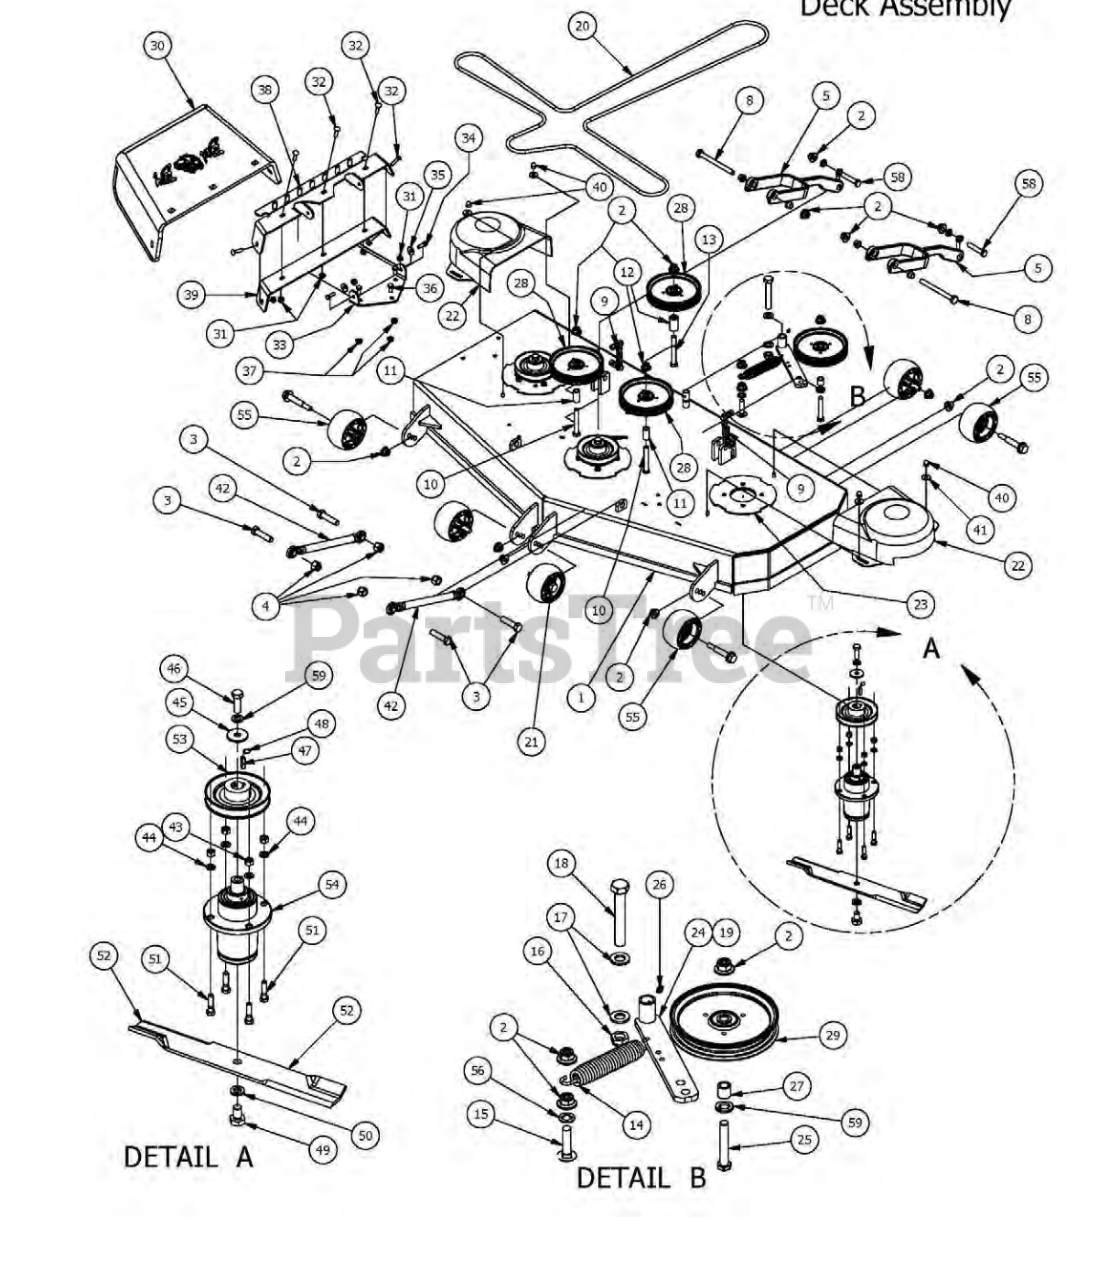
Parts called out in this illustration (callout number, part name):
1	ZT/Maverick 54" Deck
2	1/2-13 Nylon Flange Nut
3	5/8" x 2 1/2" Grade 5 Hex Bolt (Coarse)
4	5/8 Std NC Nylock Nut
5	Deck Arm Assembly
6	Flange Bushing For Lower Deck Arm
7	Flange Bushing For Upper Deck Arm
8	1/2" x 5 1/2" Bolt
9	6 Link Chain assembly
10	1/2 x 3 1/2 Flange Bolt Grade 8
11	502 ID X.750 OD X 1.500 Long Spacer
12	1 3/4" Pulley Spacer
13	1/2" x 4" Bolt (Grade 8)
14	2009 Deck/Pump Idler Spring
15	1/2 x 2" Carriage Bolt
16	5/8-11 Nylon Insert Jam Half Nut
17	.630 ID Plastic Washer
18	5/8" x 4" Hex Bolt
19	Deck Idler Assembly (Components 2,24,25,26,27,29,59)
20	B155.75 Deck Belt
21	Deck Wheel Bolt
22	2014 ZT Pulley Cover
23	Deck Spindle Support Plate
24	Deck Idler
25	1/2-13 x GR 5 Hex Bolt Zinc
26	1/4" Press in Grease Fitting
27	Spacer 3/4 OD x 1/2 1D x 314 Length
28	5-3/4 Idler Pulley
29	5-3/4 Idler Pully Don-Dye
30	Rubber Discharge Chute
31	5/16" Nylon Flange Nut
32	5/16" x 1 1/4" Carriage Bolt
33	Discharge Chute Hanger (Deck Mounted)
34	5/16" x 1" Bolt
35	.360 ID Plastic Washer
36	3/8" x 3/4" Hex Bolt
37	3/8" Flange Nut
38	60" Discharge Chute Upper Hanger
39	60" Lower Hanger
40	Acorn nut-pulley Cover
41	360 ID Plastic Washer-Black
42	Turnbuckle
43	3/8" Hex Nut
44	3/8" Lock Washer
45	1/2 Belleville Washer
46	1/2"-20 x 1 1/2 - Grade 5 Fine Thread Bolt
47	1/4" x 1" Key
48	5/16 Set Screw
49	5/8" x 1 1/2" Grade 8 Hex Bolt (Fine)
50	5/8" Lock Washer
51	3/8" x 1 1/2" Hex Bolt
52	54" Deck Fusion Blade For Outlaw
53	5" Spindle Deck Pulley
54	Spindle Assembly
55	Anti-Scalp Rollers
56	517 Square Hole Round Washer
57	Deck Wheel Bolt
58	1/2" x 3" Hex Bolt
59	1/2" Lock Washer Zinc
